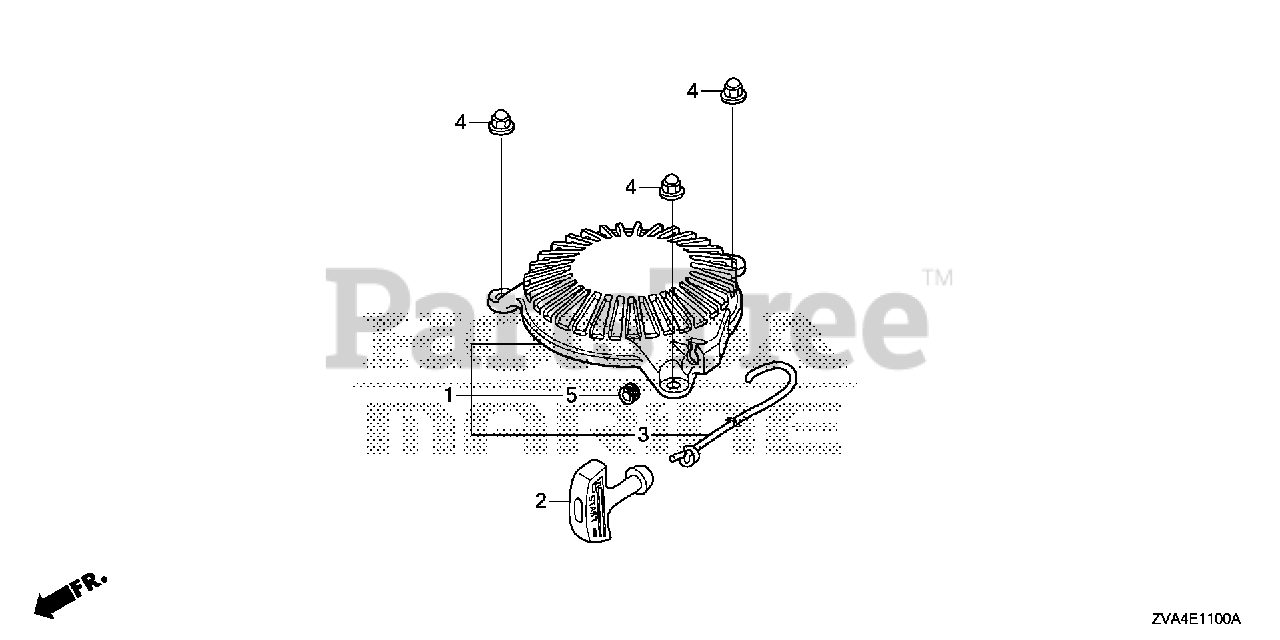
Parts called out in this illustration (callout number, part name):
1	STARTER ASSY., RECOIL
2	KNOB, STARTER
3	ROPE, RECOIL STARTER
4	NUT, FLANGE CAP (5MM)
5	GUIDE, ROPE
